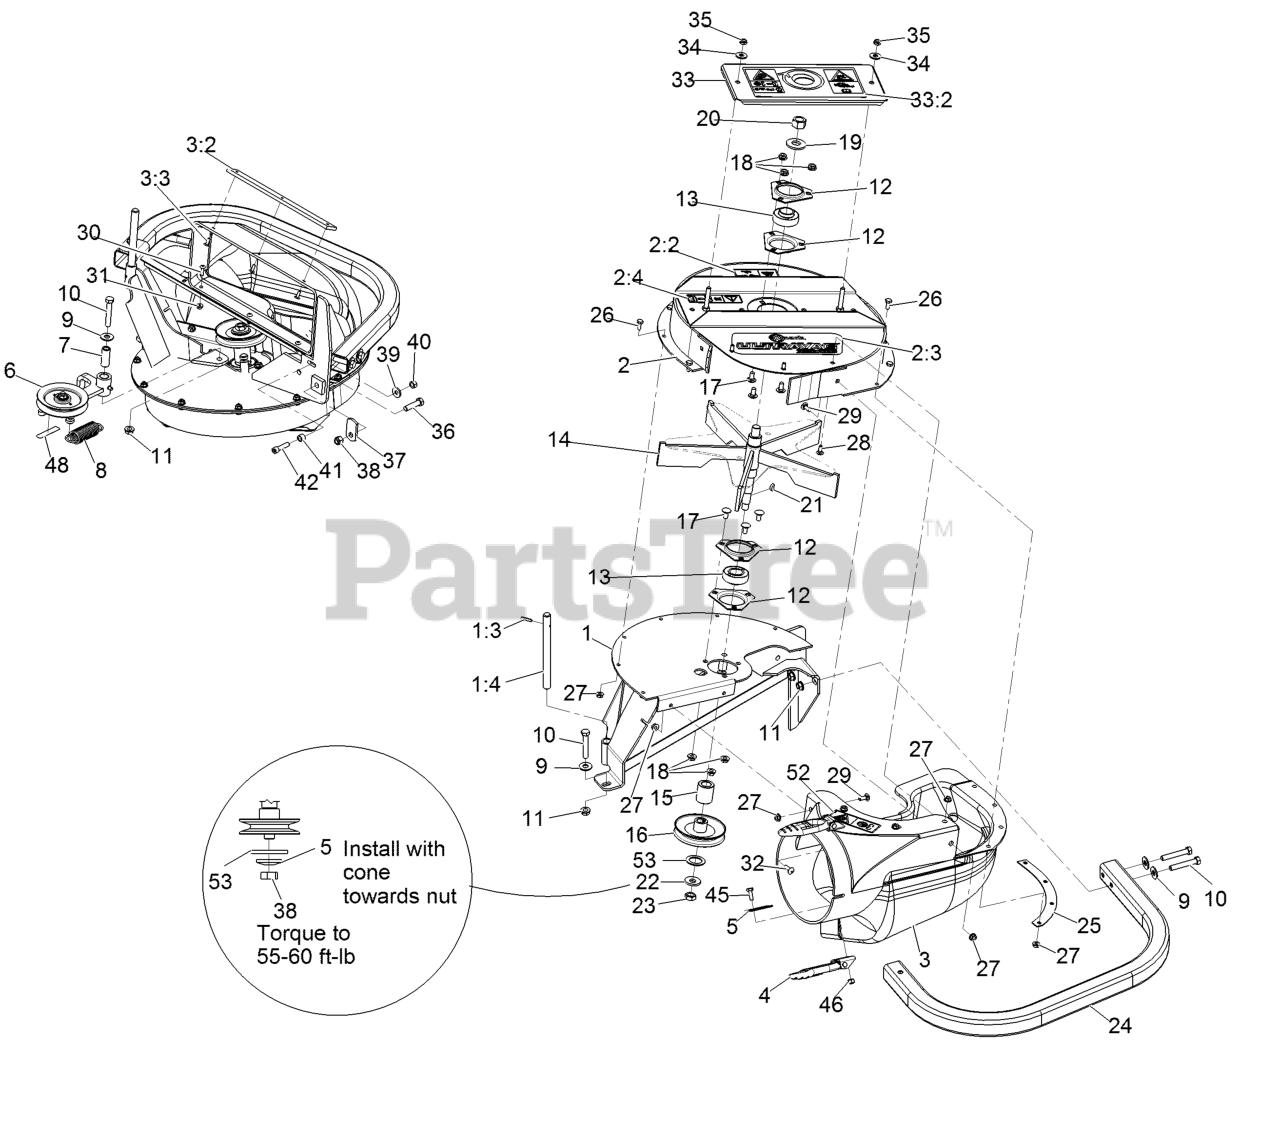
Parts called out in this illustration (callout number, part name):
1	Wld,Frame Lg Blower
1:3	Rollpin 3/16 X 7/8
1:4	Shaft-Catcher, Grass
2	ASM-Upper Housing Large
2:2	Decal-Warning, Traction
2:3	Decal-Ultravac X-Series
2:4	Decal-Missing, Cover
3	Asm, Blower Chute
3:2	Plate, Reinforcement
4	Latch-Rubber
5	Plate-Backing
6	ASM, Idler
7	Bushing
9	Washer-3/8 Std
10	Screw-HH 3/8-16 X 2 1/4
11	Nut-Whizlock 3/8-16
12	Housing-Flange
13	Bearing
14	Impeller
17	Bolt-Carriage 5/16-18 X 5/8
18	Nut-Whizlock 5/16-18
19	Washer-Spring Disc 5/8
20	Nut-Hex 5/8-18
21	Key-Woodruff 3/16 X 5/8
22	Washer-Spring Disc 1/2
23	Nut-Jam 1/2-20
25	Plate-Backing, Blower
26	Screw-HH 1/4-20 X 5/8
27	Nut-Whizlock 1/4-20
28	Bolt-Carriage 1/4-20 X 5/8
29	Bolt-Carriage 1/4-20 X 3/4
30	Screw-Truss Head #10-24 X 3/4
31	Nut-Whizlock #10-24
32	Screw-PPH 1/4-20 X 3/4
33	Cover, Bearing W/Decal
33	Cover, Bearing With Decal
33:2	Decal, Warning
34	Washer-5/16 Std
35	Nut-Nyloc 5/16-18 Thin
36	Screw-HH 3/8-16 X 1 1/2
37	Latch-Catcher, Grass
38	Nut-Nyloc 3/8-16
39	Washer-Spring Disc 5/16
40	Nut-Hex 5/16-18
41	Bushing
42	Screw-Sh 5/16-18 X 1 1/4
45	Screw-HH 1/4-20 X 3/4
46	Nut-Nyloc 1/4-20
48	Decal-Warning
52	Decal-Warning
